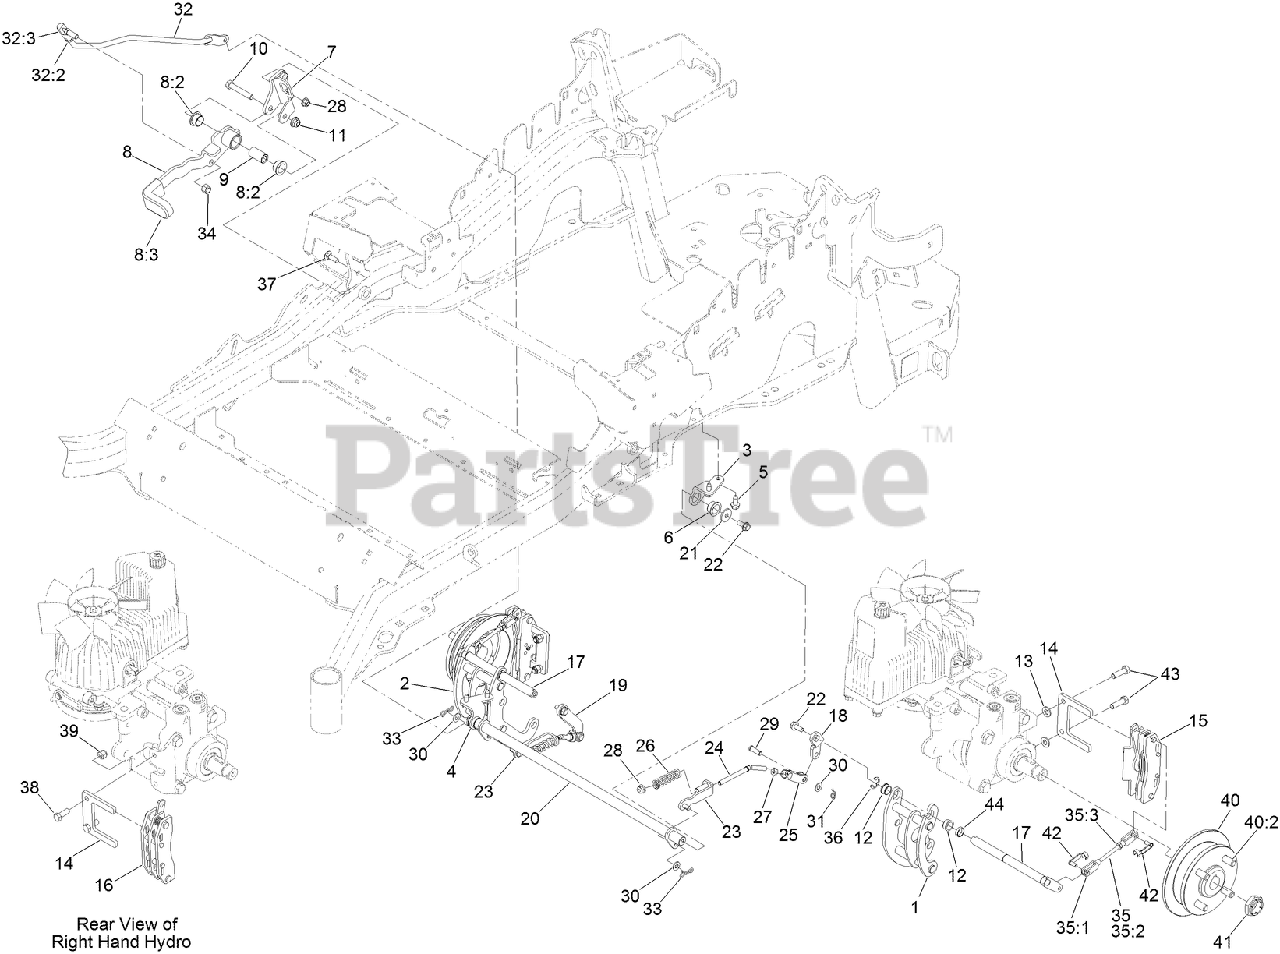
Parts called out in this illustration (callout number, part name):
1	MOUNT-BELLCRANK, LH
2	MOUNT-BELLCRANK, RH
3	MOUNT-PIVOT, LH
4	MOUNT-PIVOT, RH
5	SCREW-HWHTF
6	BUSHING-FLANGE
7	BRACKET-MOUNT
8	BRAKE LEVER ASM W/ GRIP
8:2	BUSHING-FLANGE
8:3	GRIP-LEVER
9	HANDLE-PIVOT, BRAKE
10	SCREW-HH
11	NUT-HF, NI
12	BUSHING
13	WASHER-FLAT
14	PLATE-MOUNT, BRAKE
15	CALIPER-BRAKE
16	CALIPER-BRAKE, RH
17	BELLCRANK
18	ARM-INNER, LH
19	ARM-INNER, RH
20	SHAFT-CROSS
21	WASHER-FLAT
22	SCREW-HHF
23	BRACKET-L
24	LINKAGE-MID
25	YOKE-OFFSET
26	SPRING-COMPRESSION
27	NUT-JAM
28	NUT-HF, NI
29	PIN-CLEVIS
30	WASHER-PLAIN
31	PIN-COTTER, LOCKING
32	FRONT LINKAGE ASM
32:2	END-TIE ROD, RH
32:3	NUT-HJ
33	PIN-COTTER, LOCKING
34	NUT-LOCK
35	REAR LINKAGE ASM
35:2	LINKAGE, REAR
35:3	NUT-JAM
36	E-RING
37	BOLT-CARR
38	SCREW-HH
39	NUT-LOCK, NI
40	WHEEL HUB ASM
40:2	STUD-WHEEL
41	LOCKNUT
42	PIN-CLEVIS, SPRING
43	SCREW-LOCK, PATCH
44	SPACER
